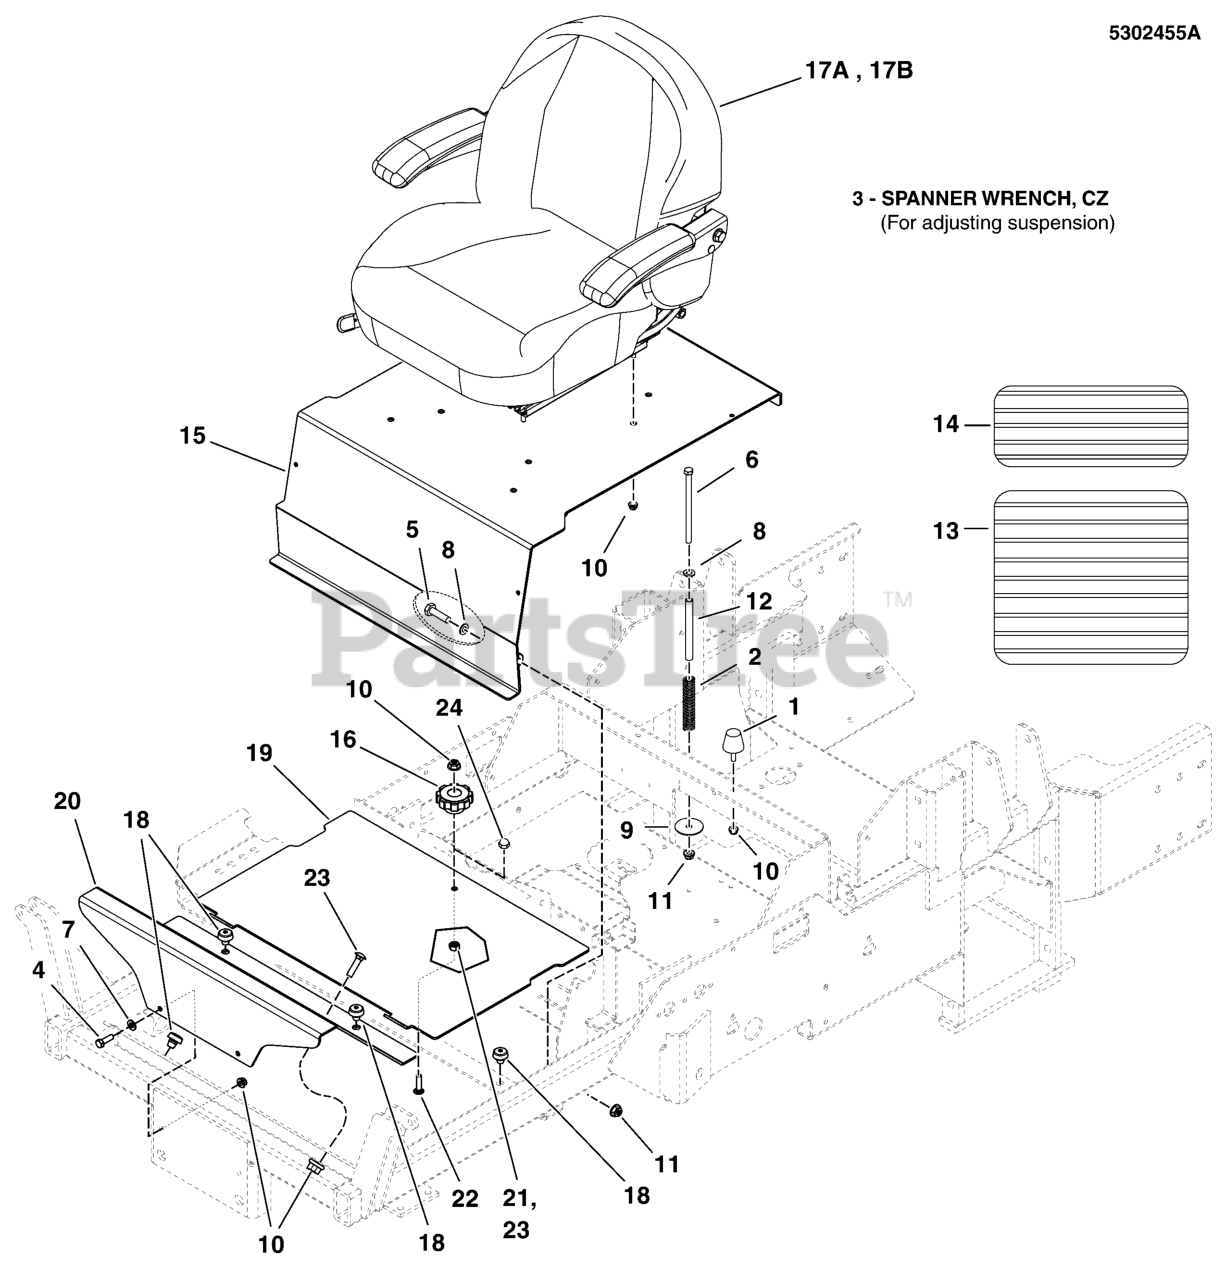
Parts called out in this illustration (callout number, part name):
1	BUMPER, RUBBER 5/16-18
2	SPRING, COMP, .835 X.105 X4.26
3	WRENCH, SPANNER, CZ
4	BOLT, 5/16-18 X 1" GRD5 YZ
5	BOLT, 3/8-16 X 3-1/2" GD5 CZ
6	BOLT, 3/8-16 X 6" GD5 CZ
7	WASHER, 5/16" SAE
8	WASHER, 3/8 SAE
9	WASHER, .39 X 2.50 X .125
10	NUT, 5/16-18 HEX NYLOCK FLANGE NUT
11	NUT, 3/8 - 16 HEX NYLOCK FLANGE
12	SPACER, .38 X .50 X 5.06, CZ
13	SAFETY WALK, FLOOR PLATE, S50X, 10X17.13
14	SAFETY WALK, FLOOR REST, 16.00 X 6.00
15	WELD, SEAT PLATE IS5100Z - RED
16	KNOB-INT THR .312-18 4-ARM 2.12WD 1.06LG
17A	SEAT, IS3100Z / IS5100Z
17B	SEAT, HIGH BACK, SEAT INC
18	MNT, VBRTN, RBBR
19	PLATE, FLOOR REMOVABLE, IS5100Z - RED
20	PLATE, FLOOR RIGID, IS5100Z - RED
21	NUT, 5/16-1/8, HEX, CNTR LK, ZINC PHOS/OIL
22	BOLT, 5/16-18 X 1-1/4, CARRIAGE, GD5, CZ
23	BOLT, 5/16-18 X 1, CARRIAGE, GD5, CZ
24	ACORN NUT, 5/16-18 S/S
